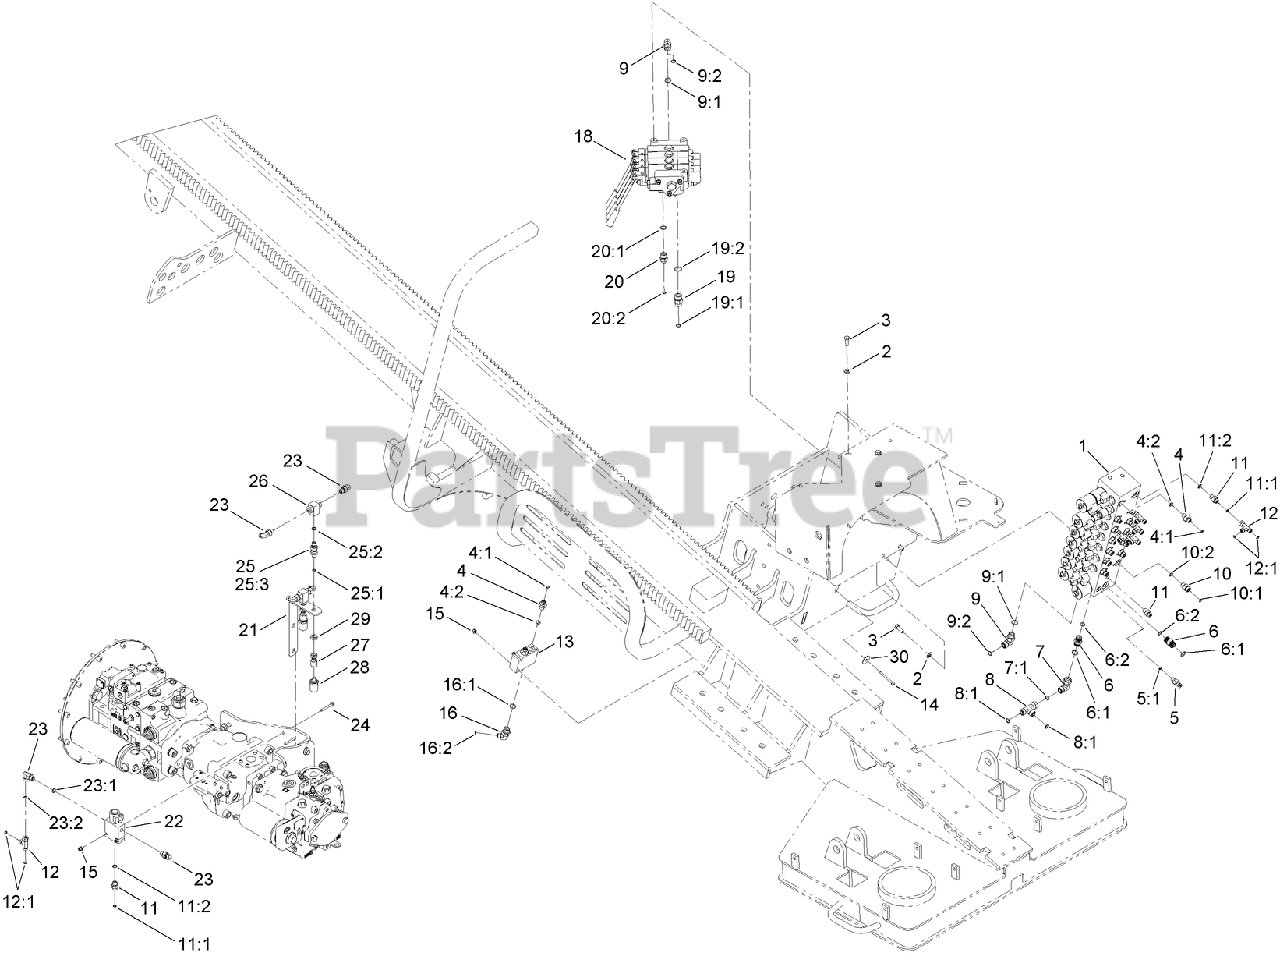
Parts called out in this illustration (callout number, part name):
1	9 SECTION HYD VALVE ASM
2	WASHER-FLAT
3	SCREW-HH
4	FITTING-STR,ORIF
4:1	O-RING
4:2	O-RING
5	FITTING-QUICK
5:1	O-RING
6	FITTING-STRAIGHT
6:1	O-RING
6:2	O-RING
7	FITTING-HYD
7:1	O-RING
8	FITTING-HYD, TEE
8:1	O-RING
9	FITTING-ELBOW-90 DEG
9:1	O-RING
9:2	O-RING
10	FITTING-STRAIGHT
10:1	O-RING
10:2	O-RING
11	FITTING-STRAIGHT
11:1	O-RING
11:2	O-RING
12	FITTING-HYD
12:1	O-Ring
13	HYD FLOW DIVIDER VALVE ASM
14	SCREW-FLANGE, METRIC
15	NUT-FLANGE, NI
16	FITTING-ELBOW 90
16:1	O-RING
16:2	O-RING
18	4 SPOOL HYD VALVE ASM
19	FITTING-STRAIGHT
19:1	O-RING
19:2	O-RING
20	FITTING-STR
20:1	O-RING
20:2	O-RING
21	BRACKET-VALVE, SHUTTLE
22	VALVE-SOLENOID
23	FITTING-ELBOW 90
23:1	O-RING
23:2	O-RING
24	SCREW-HHF
25	FITTING-STRAIGHT
25:1	O-RING
25:2	O-RING
25:3	NUT-LOCK
26	VALVE-SHUTTLE, LOAD
27	FITTING-STRAIGHT
28	TRANSDUCER
29	NUT-LOCK
30	WASHER-FLAT
